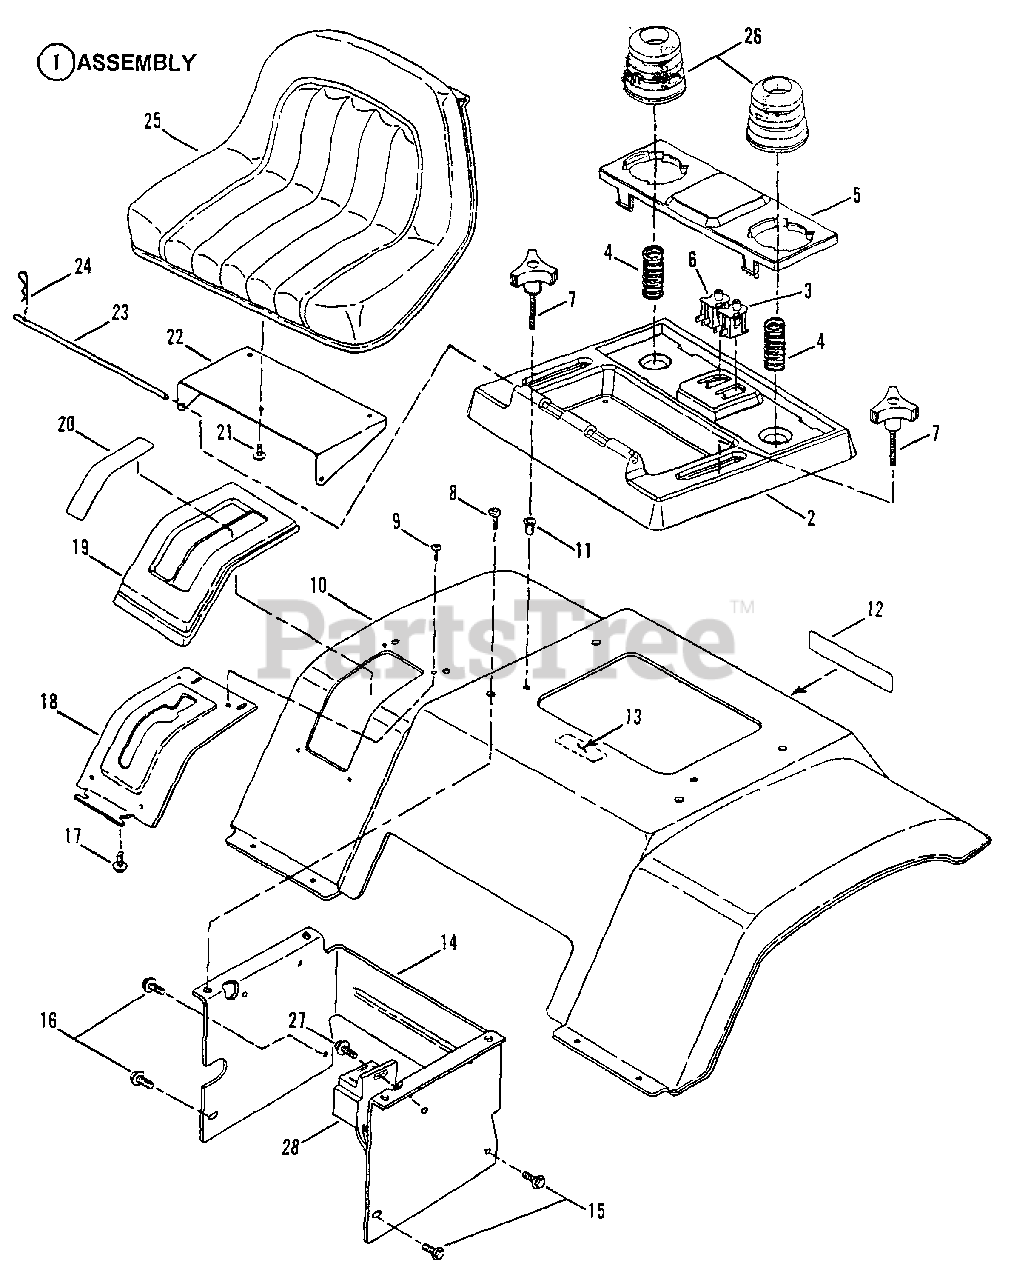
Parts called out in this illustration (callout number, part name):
1	ASSEMBLY, Seat Support (Manual PTO units)
1	ASSEMBLY, Seat Support (Electric PTO units)
2	SUPPORT, Seat
3	SWITCH, Seat, Gray, N.C.
4	SPRING
5	HOLDER, Cushion
6	SWITCH, Seat
7	KNOB, Seat Adjustment, 5/16-18 x 2"
8	SCREW, 5/16-18 x 5/8" Truss Head, Torx
9	SCREW, 1/4-20 x 5/8" Hex Washer Head, Self-Tapping
10	PAN, Seat (Fender)
11	RIV-NUT, 5/16-18
11	RIV-NUT, 5/16-18, .530" Round & Serated
12	DECAL - SNAPPER, 7.28" Molded Logo, Silver Letters & Blue Stripe
13	DECAL - CAUTION, Battery Location
14	SUPPORT, Fender
15	SCREW, 5/16-18 x 5/8" Hex Washer Head, Swage Form
16	SCREW, 5/16-18 x 1-1/4" Hex Washer Head, Swage Form
17	SCREW, #10-16 x 1/2" Hex Washer Head, Self-Tapping
18	DETENT, Shift
19	COVER, Shift
20	DECAL, Shift Cover, 5-Speed
21	BOLT, 5/16-18 x 1/2" Hex Flange Lock, Grade 5
22	BRACKET, Seat Support
23	ROD, Seat Hinge
24	PIN, 3/32 x 1-1/2" Hair
25	SEAT, Operator, V560
25	SEAT, Operator
26	CUSHION, Seat
27	SCREW, #10-24 x 1/2" Hex Washer Self-Tap (Torx)
28	RECEPTACLE, Female Wire Harness Relay
